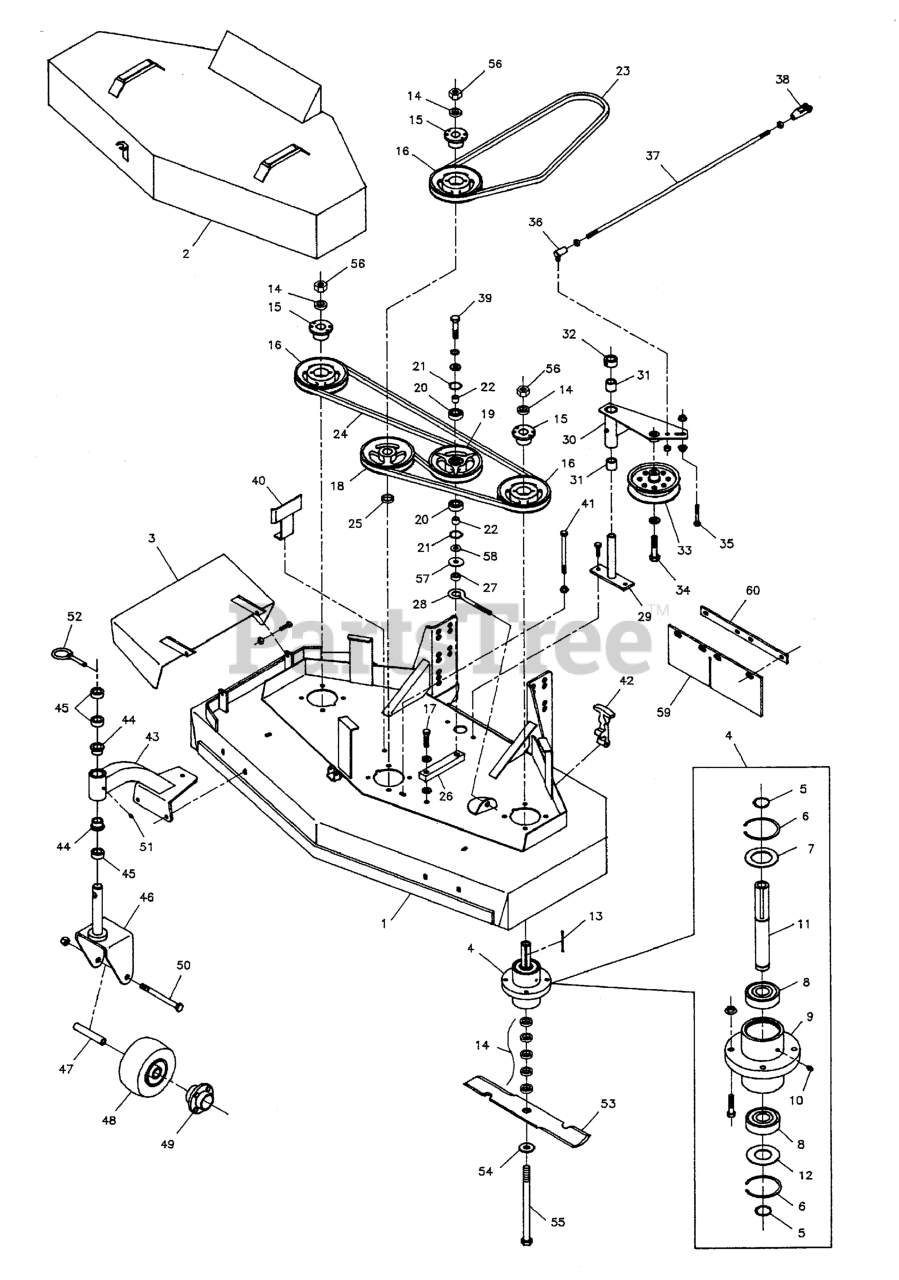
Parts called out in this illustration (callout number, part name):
1	48" MOWER HOUSING ASSEMBLY
1	48" REAR DISCHARGE MOWER HOUSING
2	48" DECK GUARD
2	48" Guard
3	CHUTE, DISCHARGE WELDMENT
4	SPINDLE ASSEMBLY, Complete
5	SNAP RING, External
6	SNAP RING, Internal
7	SPINDLE WASHER, Top
8	BEARING
9	SPINDLE HOUSING
10	GREASE FITTING
11	SPINDLE SHAFT
12	SPINDLE WASHER, Bottom
13	KEY, 1/4 SQ. X 2-1/2
14	SPACER, .63 x 1.06 x .23
15	BUSHING, Tapered Hub
16	PULLEY, Spindle
17	BOLT, 7/16-20 X 1-3/4" GD.5
18	SPINDLE PULLEY
19	IDLER PULLEY, Complete
19	PULLEY, Idler
20	BEARING, BALL 11/16X1-9/16X15/32
21	SNAP RING, Internal
22	INSERT, Bearing
23	Belt, 48" Deck Drive
24	BELT, Blade Spindle
25	SPACER, 1.00 X 1.25 X .25
26	ARM, Idler
26	IDLER ARM
27	SPACER, .52 X 1.00 X .38
28	EYEBOLT, 3/8" X 6"
28	J-BOLT
29	BLADE ENGAGE PIVOT
30	Blade Engagement Shaft
31	BUSHING, Brass
32	COLLAR, 3/4" Set
33	PULLEY, V-Idler
34	BOLT, 1/2-20 x 2
35	BOLT, 5/16-18 x 2-1/4
36	BALL JOINT, 3/8" Female Studded
37	Blade Engagement Rod
38	CLEVIS, 3/8-24, Plastic
39	BOLT, 1/2-20 X 2-1/4 GD5 CZ
39	BOLT, 1/2-20 X 1-3/4" GD8 CZ
40	Belt Guide
41	BOLT, 3/8-16 x 5
42	RUBBER LATCH
43	CASTER MOUNT, Complete
44	BUSHING, FLANGE
45	SPACER, 1.02 x 1.56 x .50
46	YOKE, Caster
47	AXLE, Caster Wheel
48	WHEEL & TIRE ASSEMBLY, White, 9 x 3.5 x 4, Complete
49	4 BOLT HUB W/ BEARING
50	BOLT, 1/2-13 x 5-1/2
51	GREASE FITTING
52	PIN, Lynch
53	MOWER BLADE, 16-1/4"
54	WASHER, 5/8" USS
55	BOLT, 5/8-11 x 9-1/2
56	NUT, 5/8-11 Hex
57	WASHER, 1/2" USS
58	WASHER, 1/2 SAE
59	Rubber Flap
60	Rubber Flap Strap
